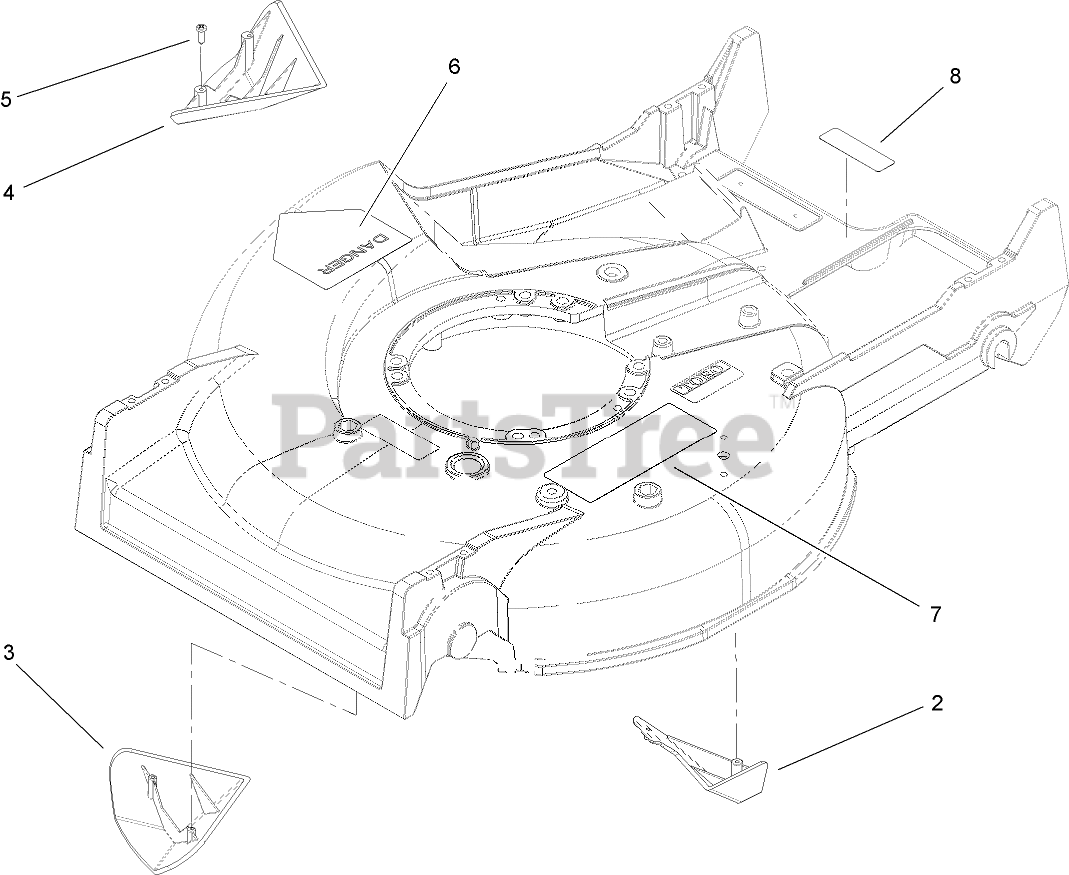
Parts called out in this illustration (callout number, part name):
2	KICKER-REAR
3	KICKER-FRONT
4	KICKER-RH
5	SCREW-PPH
6	DECAL-DANGER
7	DECAL-WARNING
8	DECAL-WARNING
